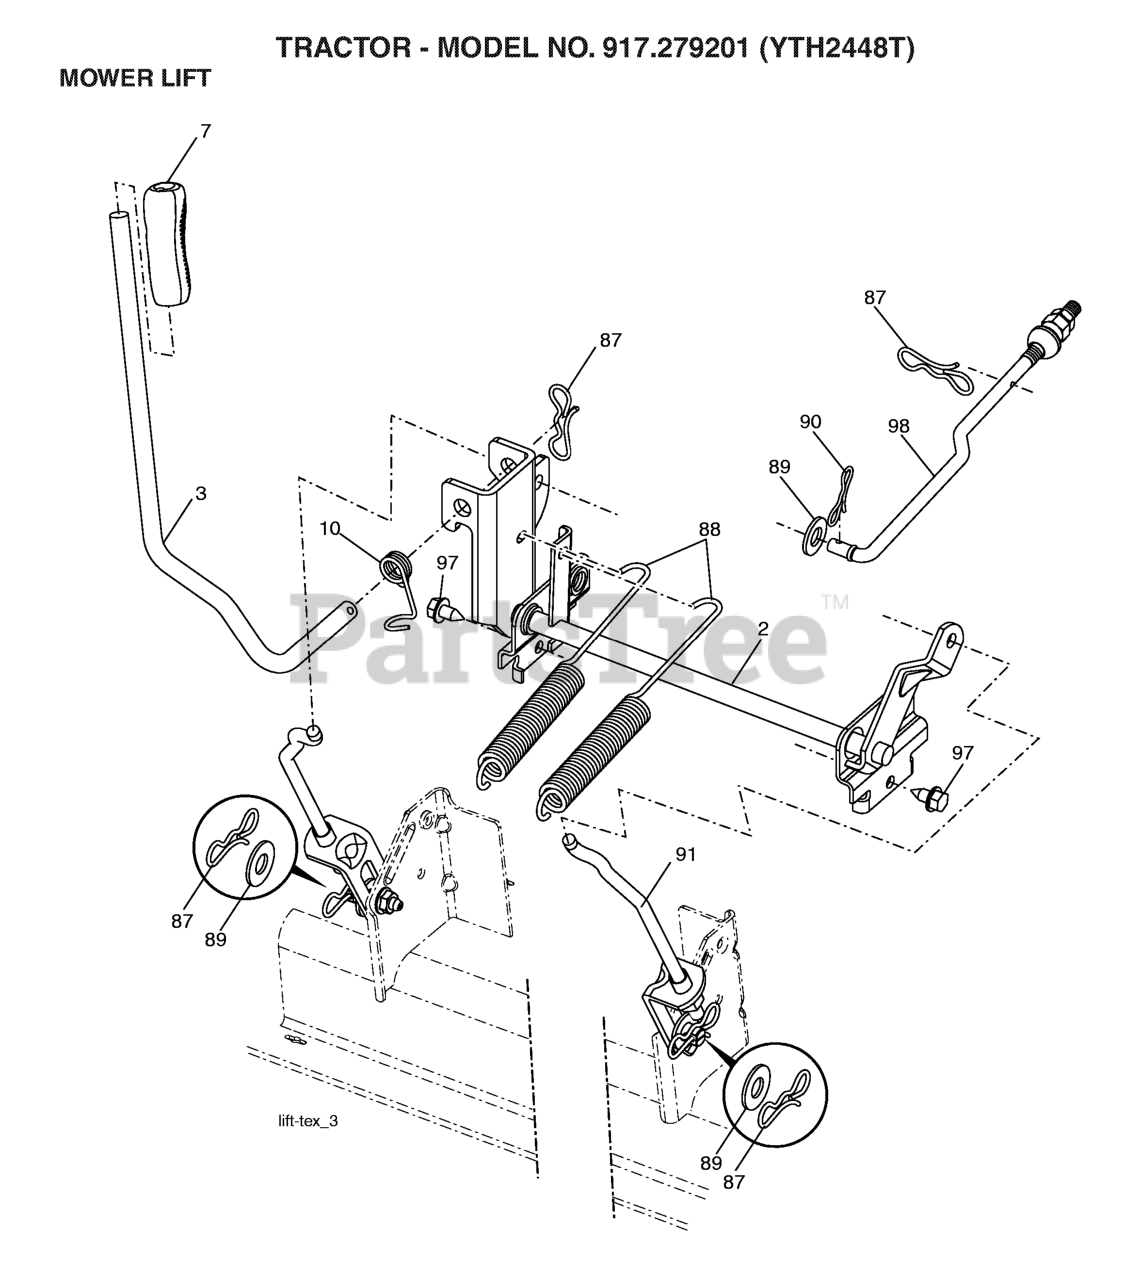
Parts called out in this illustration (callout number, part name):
2	SHAFT.ASM.LIFT.CROSS.H
3	LEVER.LIFT.HANDLE.GT
7	GRIP.LEVER.5625.ID
10	SPRING.TORSION.LIFT.HANDLE
87	PIN.COTTER.7/16.BOW TI.
88	SPRING.LIFT.ASSIST.GT2
89	WASHER.CLEAR.ZINC
90	PIN.COTTER.5/16.BOW TI
91	LINK.ASM.LIFT.REAR
97	SCREW 3/8-16X3/4
98	LINK.ASM.SUSP.FRONT.MWR.10.5
